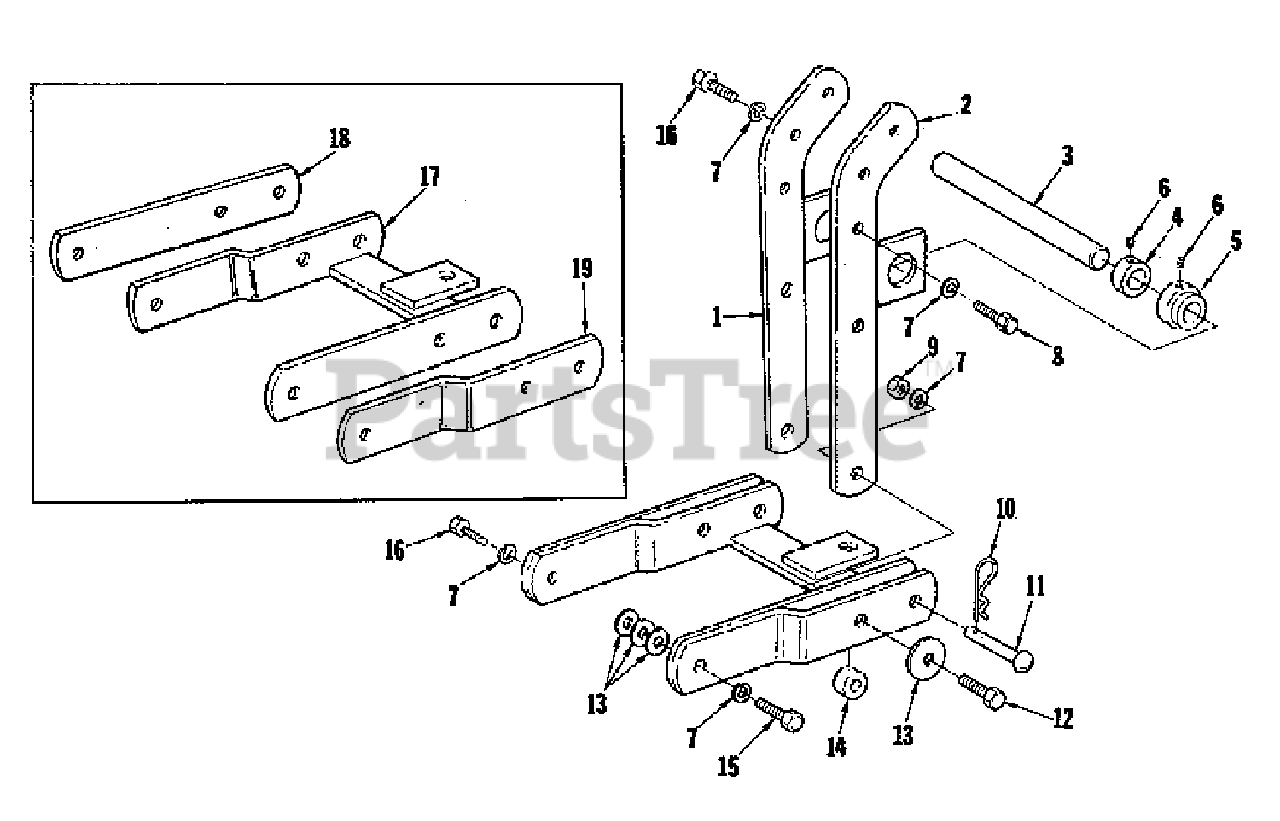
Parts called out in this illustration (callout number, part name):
1	ARM ASSEMBLY, L.H.
2	ARM ASSEMBLY, R.H.
7	WASHER, Lock
8	SCREW, Hex Head Cap
10	CLIP, Spring
11	PIN, Round Head
12	SCREW, Hex Head Cap
13	WASHER, Flat
15	SCREW, Hex Head Cap, 7/16-14 x 1-1/2
16	SCREW, Hex Head Cap
17	DRAWBAR ASSEMBLY
